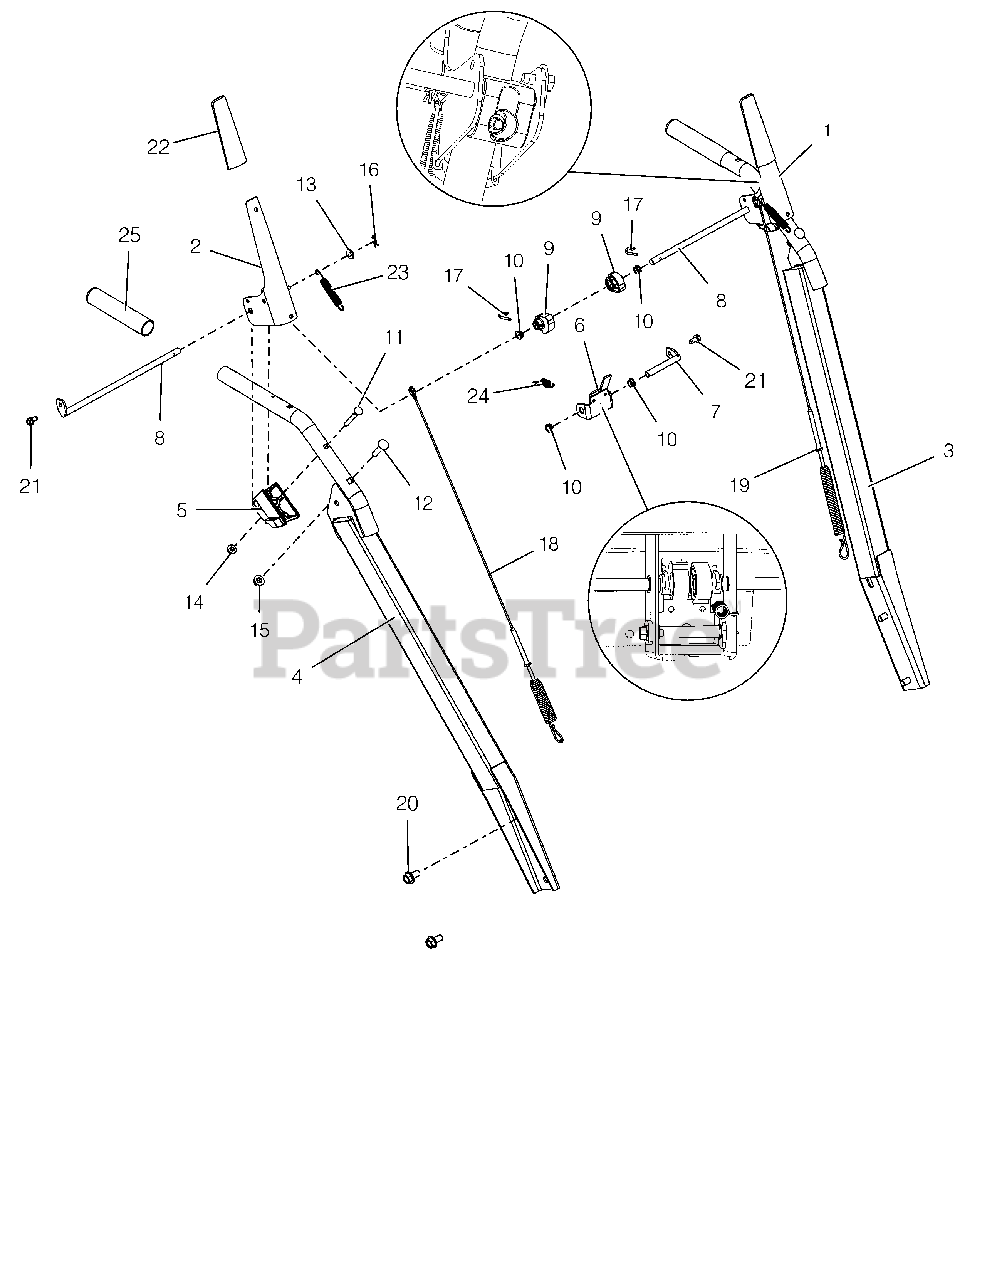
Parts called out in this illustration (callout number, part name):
1	LEVER, CLUTCH-LH
2	LEVER, CLUTCH-RH
3	HANDLEBAR, HEAVYDUTY-PRO LH
4	HANDLEBAR, HEAVYDUTY-PRO-RH
5	BLOCK, CLUTCH PADDLE
6	BRACKET, INTERLOCK ARM
7	ROD, INTERLOCK PIVOT
8	ROD, PADDLE MOUNT - PRO
9	CAM, INTERLOCK
10	BUSHING, POLYLINER-.38 SNAPIN
11	BLT-RDHDXLSQNK .25-20X2.0 G5YZ
12	@BLT-RDHDSQNK .31-18X1.50 G5YZ
13	@WSHR-FL-STL.281X.62X.065 YWZC
14	NUT-LK-CTR-FLG .25-20 YWZC
15	@NUT-LK-TOP-FLG .31-18 YWZC
16	PIN-HAIR INT .06X.18X.77
17	PIN, SPRING CLIP
18	CABLE, AUGER (DELUXE & PRO)
19	CABLE, UPPER TRACTION
20	BLT-SERHFWH .38-16X.75 YWZC
21	SCR-TAP .25-20X.50 HWH TR YWZ
22	SLEEVE, CLUTCH PADDLE-GRAY
23	SPRING, EXTENSION
24	SPRING-EXT .047X.438X1.45
25	GRIP,HANDLE-GRAY
